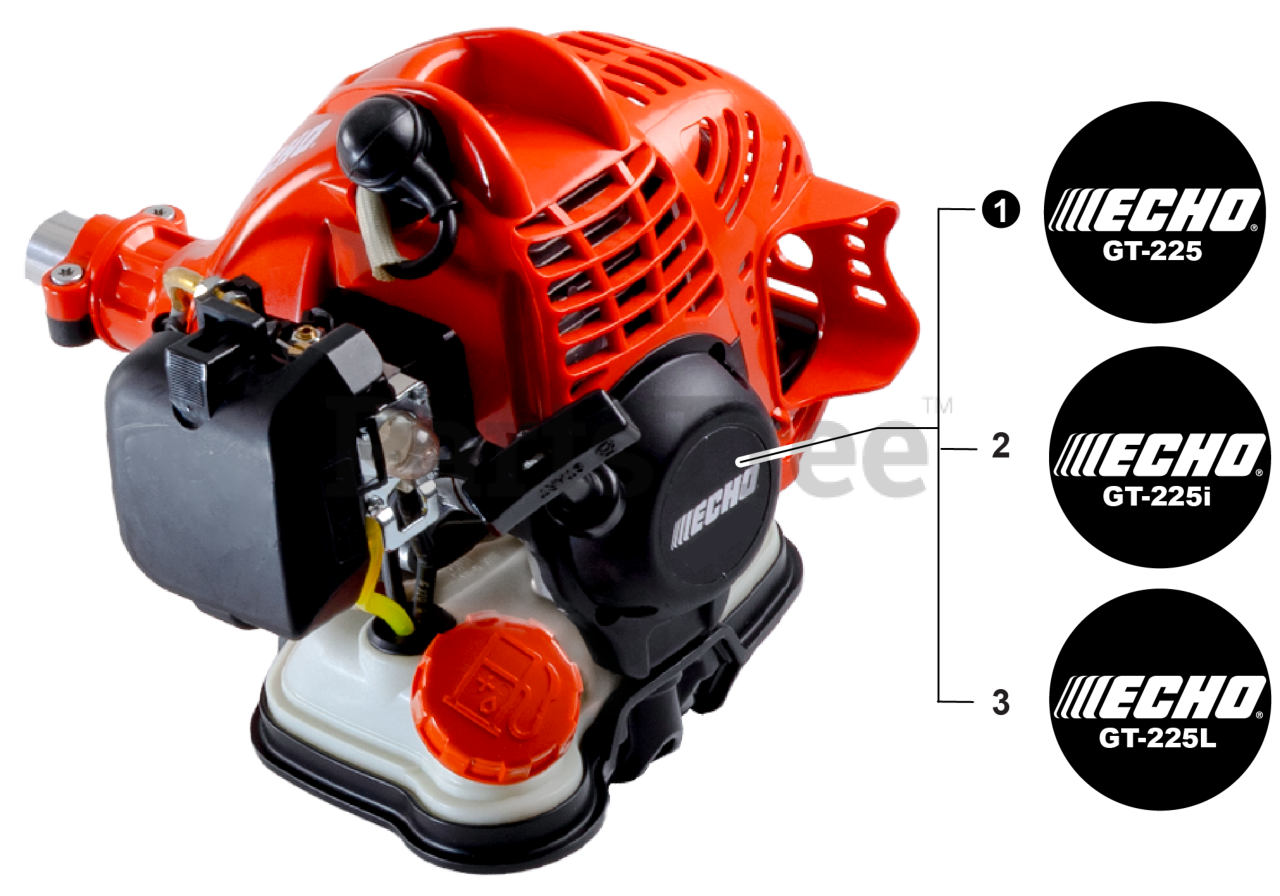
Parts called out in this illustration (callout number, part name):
1	LABEL - STARTER - GT-225
2	LABEL - STARTER - GT-225I
3	LABEL - MODEL - GT-225L
